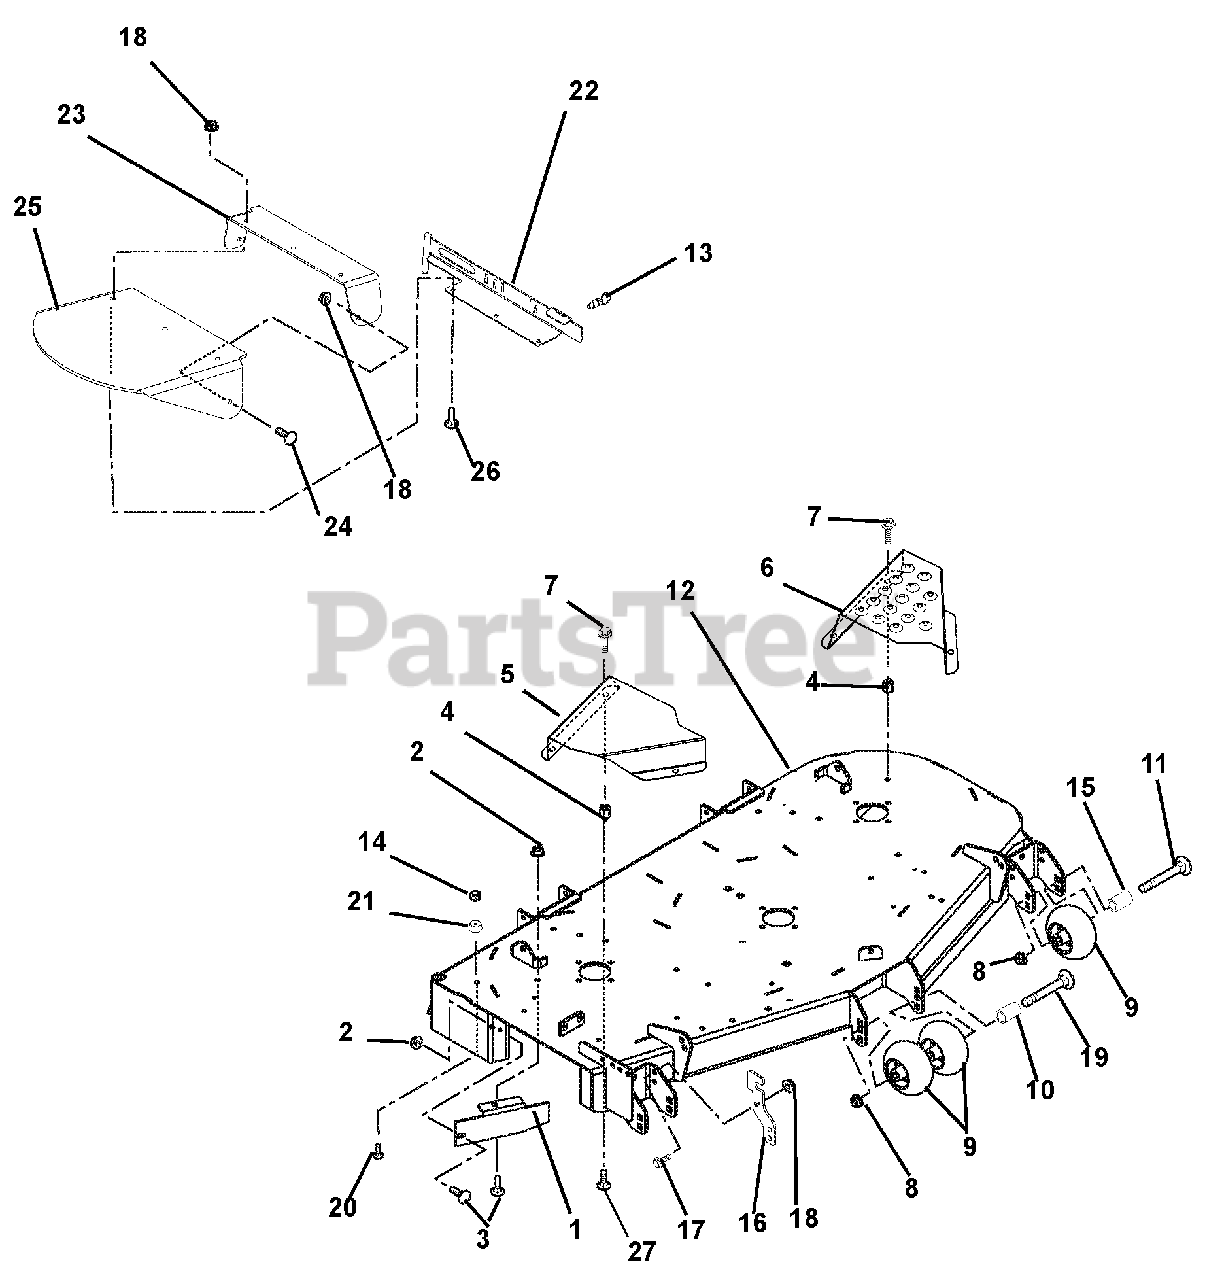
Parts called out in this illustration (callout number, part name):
1	52-in. Discharge Baffle (992212)
2	Nut, .31-18 Nyloc Flange
3	Bolt, Round Head Square Neck .31-18 x 1.00 Grade 5
4	Nut, Heavy Hex .38-16
5	52-in. Right Hand Spindle Guard (992212)
6	52-in. Left Hand Spindle Guard (992212)
7	Nut, Spin Lock-Flange .375-16
8	Nut .50-13 Nyloc Flange
9	Anti-Scalp Wheel
11	Bolt, Round Head Square Neck .50-13 x 5.00
12	52-in. Pro-Master 200 Side Discharge Deck Weldment (992212)
13	Pin, Plunger Pull .50-13 Thread x .310 Diameter
14	Nut, Locking, Center .31-18
15	Spacer, .510 x .625 x 3.35
16	Chute, Storage Bracket
17	Bolt, Hex .38-16 x 1.00 Grade 5
18	Nut, .38-16 Nyloc Flange
19	Bolt, Round Head Square Neck .50-13 x 8.50
20	Bolt, Round Head Square Neck .31-18 x 1.50
21	Bumper, Recessed 1.50 x .63 , .31 Thru Hole
22	Weldment, 52-inch and 60-inch Discharge Chute Mounting (992210, 212, 217)
23	Rubber Discharge Chute Support
24	Bolt, Round Head Square Neck .38-16 x 1.00 Grade 5
25	Chute, Rubber Discharge
26	Bolt, Round Head Square Neck .38-16 x 1.25 Grade 5
27	Bolt, Hex .38-16 x 1.25 Grade 5
